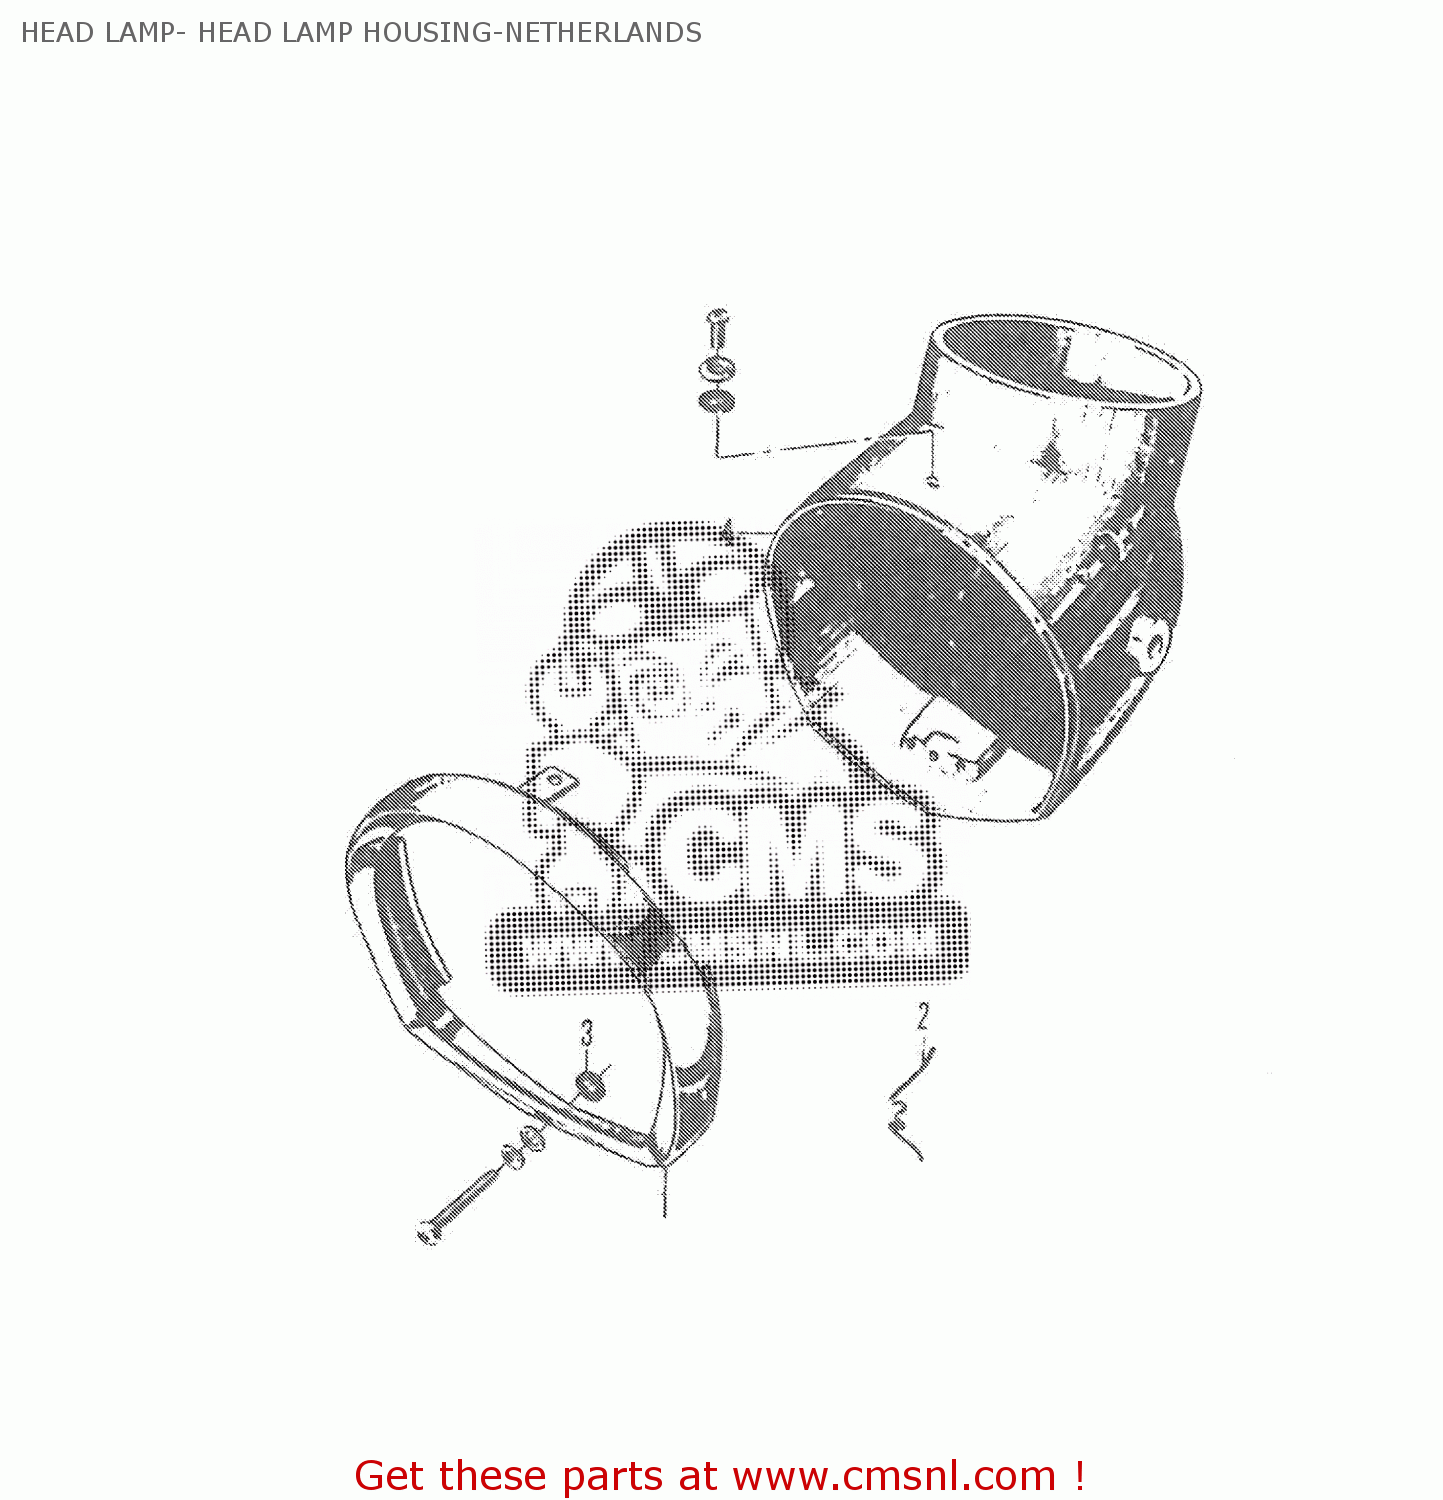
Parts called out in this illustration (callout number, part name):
1	HEAD LAMP RIM
2	SPRING,HEAD LA
3	HEAD LAMP FITTING SPACER
4	HEAD LAMP HOUSING
